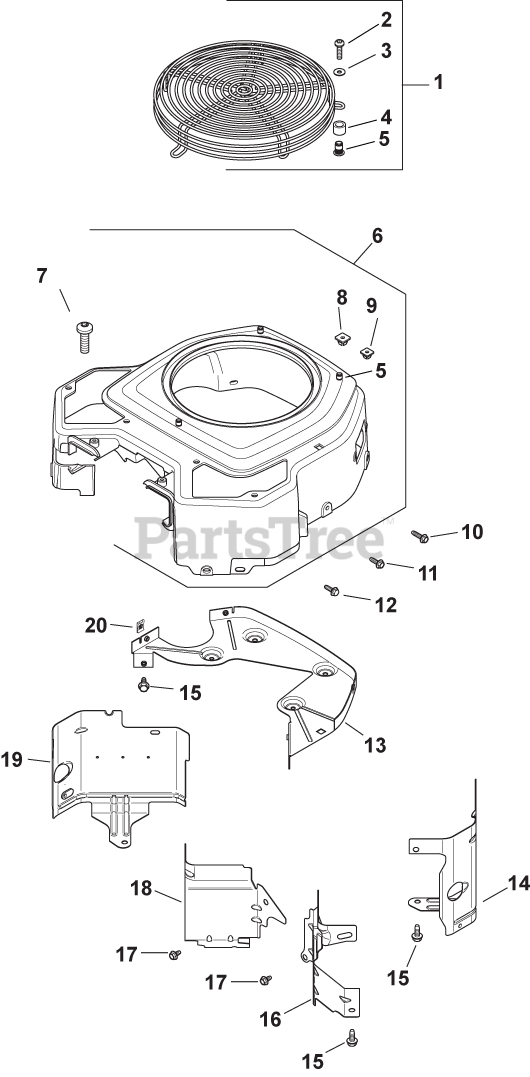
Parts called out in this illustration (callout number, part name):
1	KIT, GUARD
2	SCREW, PAN HEAD-USE 25 086 160-S
3	WASHER, FLAT 7/32"
4	SPACER USE 25 112 30-S
5	INSERT, THREADED USE 25 332 19-S
6	KIT, BLOWER HOUSING ASSEMBLY USE 24 027 448-S
7	SCREW, SKT SET #10-24X1/4"
8	NUT, PLASTIC (KM)-USE 25 100 37-S
9	NUT, PLASTIC
10	SCREW - USE M-545016-S
11	SCREW, FLG THD FRM M5X.8X20-(#25086399S)
12	SCREW,FLG THD FRM M5X0.8X16-(#25086398S)
13	PLATE, BACKING-USE 24 146 59-S
14	BAFFLE, LEFT BARREL -USE 24 063 88-S
15	SCREW,FLG THD FRM M6X1.0X16-(#25086397S)
16	BAFFLE, VALLEY #2 SIDE-USE 24 063 94-S
17	SCREW, FLG THD FRM M5X.8X10
18	BAFFLE, VALLEY (CV)-USE 24 063 93-S
19	BAFFLE, RIGHT BARREL-USE 24 063 85-S
20	CLIP, REPAIR (SPEED NUT)
